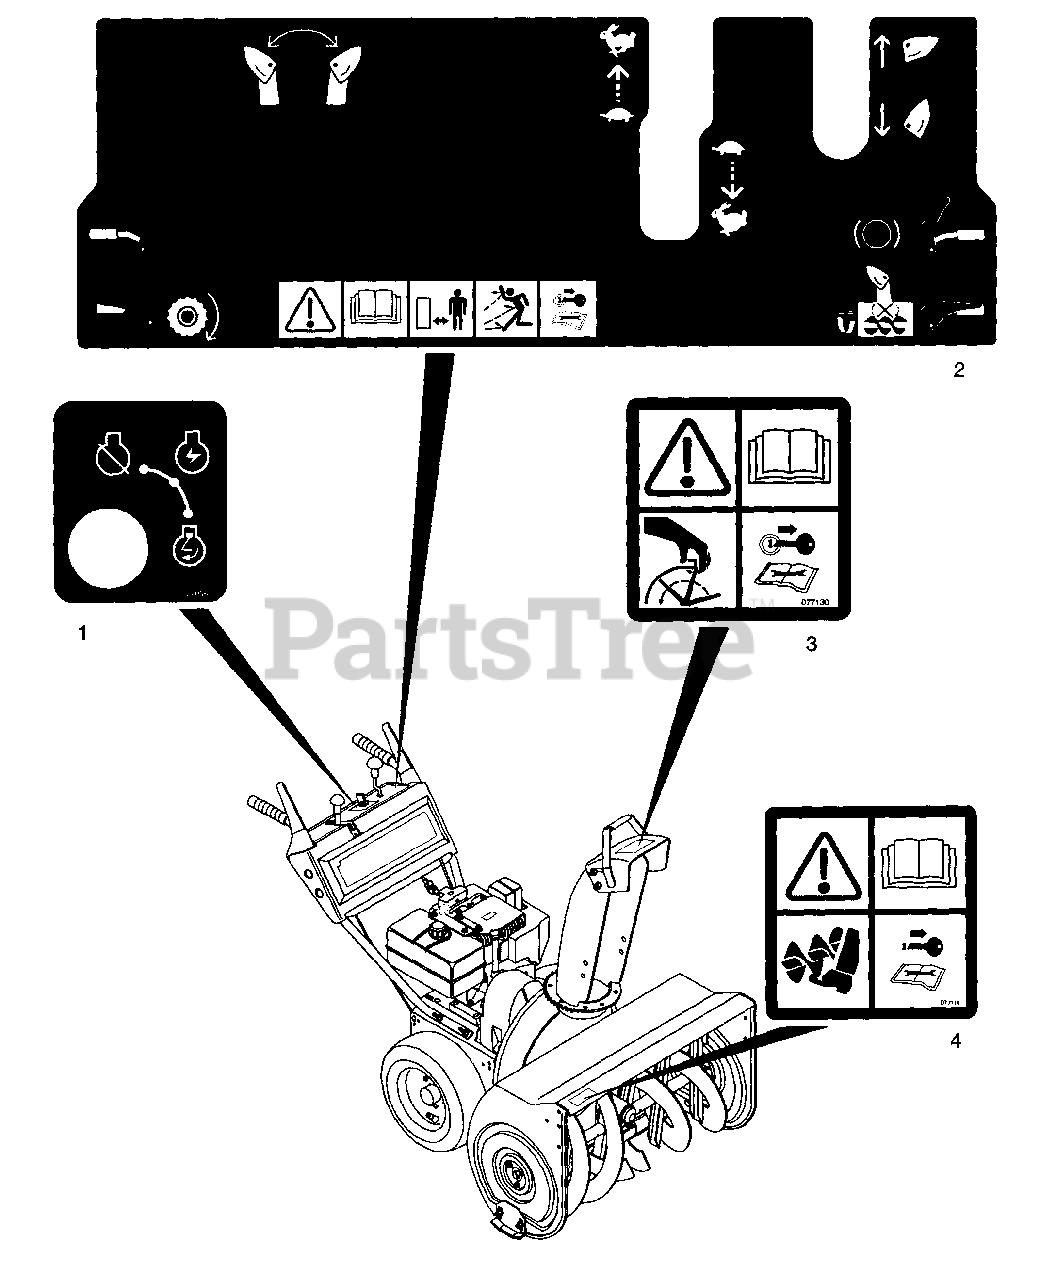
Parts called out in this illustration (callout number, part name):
1	DECAL 924-SWITCH
2	DECAL, DASH - CE
3	DECAL, DANGER IMPELLER - CE
4	DECAL, DANGER AUGER - CE
